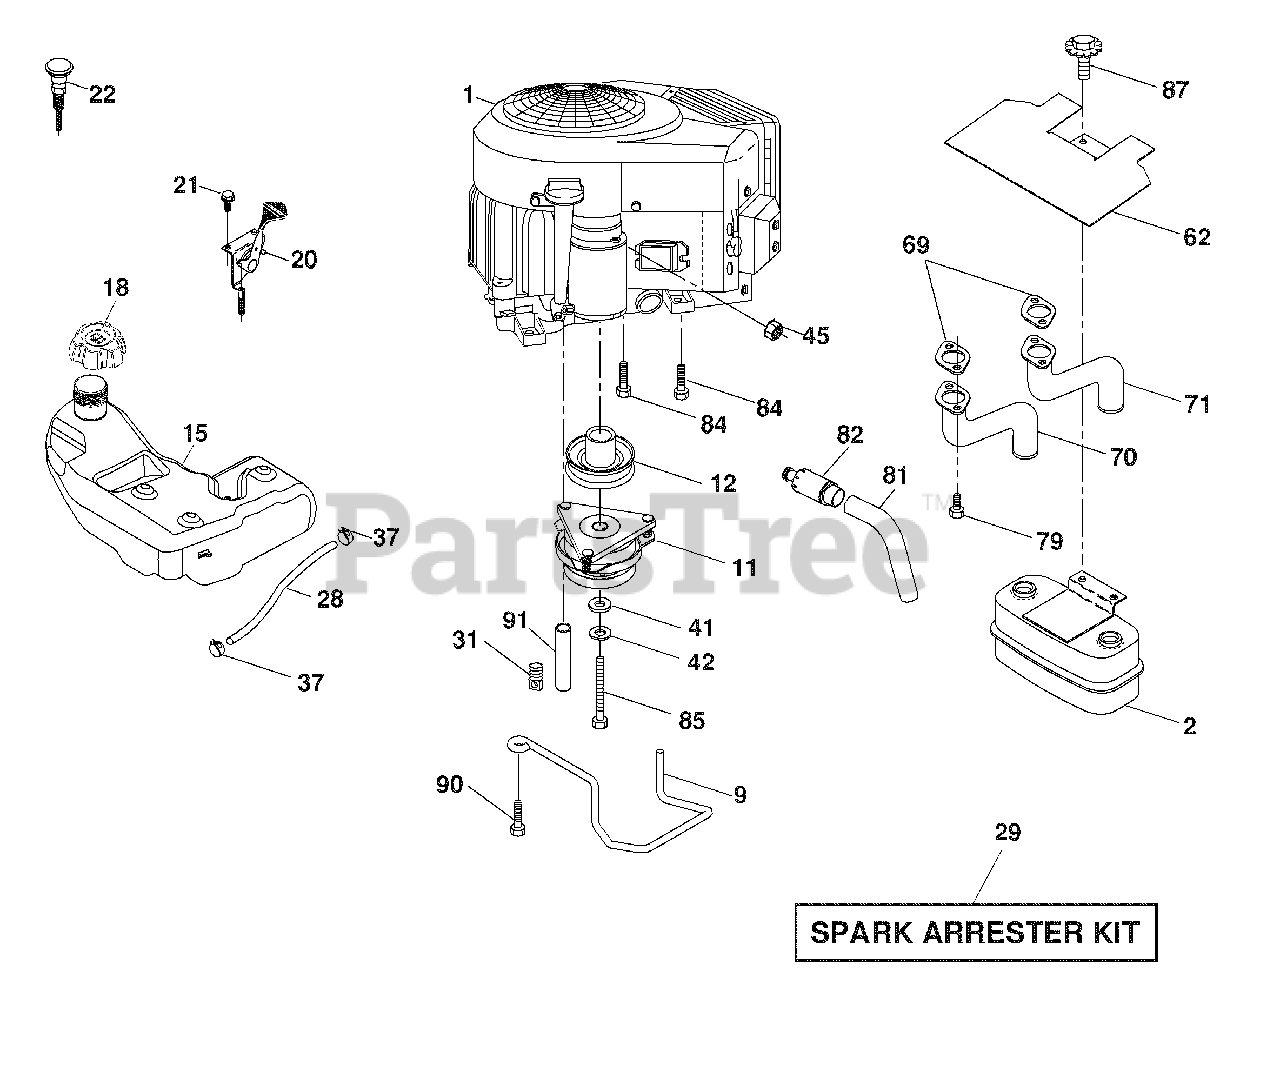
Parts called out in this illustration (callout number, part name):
9	Keeper Belt Engine
11	Clutch Electric
12	Pulley Engine
15	Tank Fuel 4.0
18	Cap Asm
20	Control Throttle
21	Screw #10 x 0.750
22	Control Choke
28	Fuel Line
29	Spark Arrester Kit
31	Clip Push-In
37	Clamp Hose
41	Washer 1-1/2 OD x 15/32 ID x .250
42	Washer Lock 7/16
45	Nut Keps Hex 1/4-20 unc
62	Shield Heat Muffler
70	Tube Exhaust LH
71	Tube Exhaust RH
79	Screw Socket Head 5/16-18 x 1
81	Tube Drain Oil Easy
82	Plug Drain Oil Easy
84	Screw 3/8-16 x 1-1/4
85	Bolt Hex 7/16-20 x 3.75 Gr. 5
87	Bolt 5/16-18 unc x 1 w/Sems
90	Screw 3/8-16 x 1
